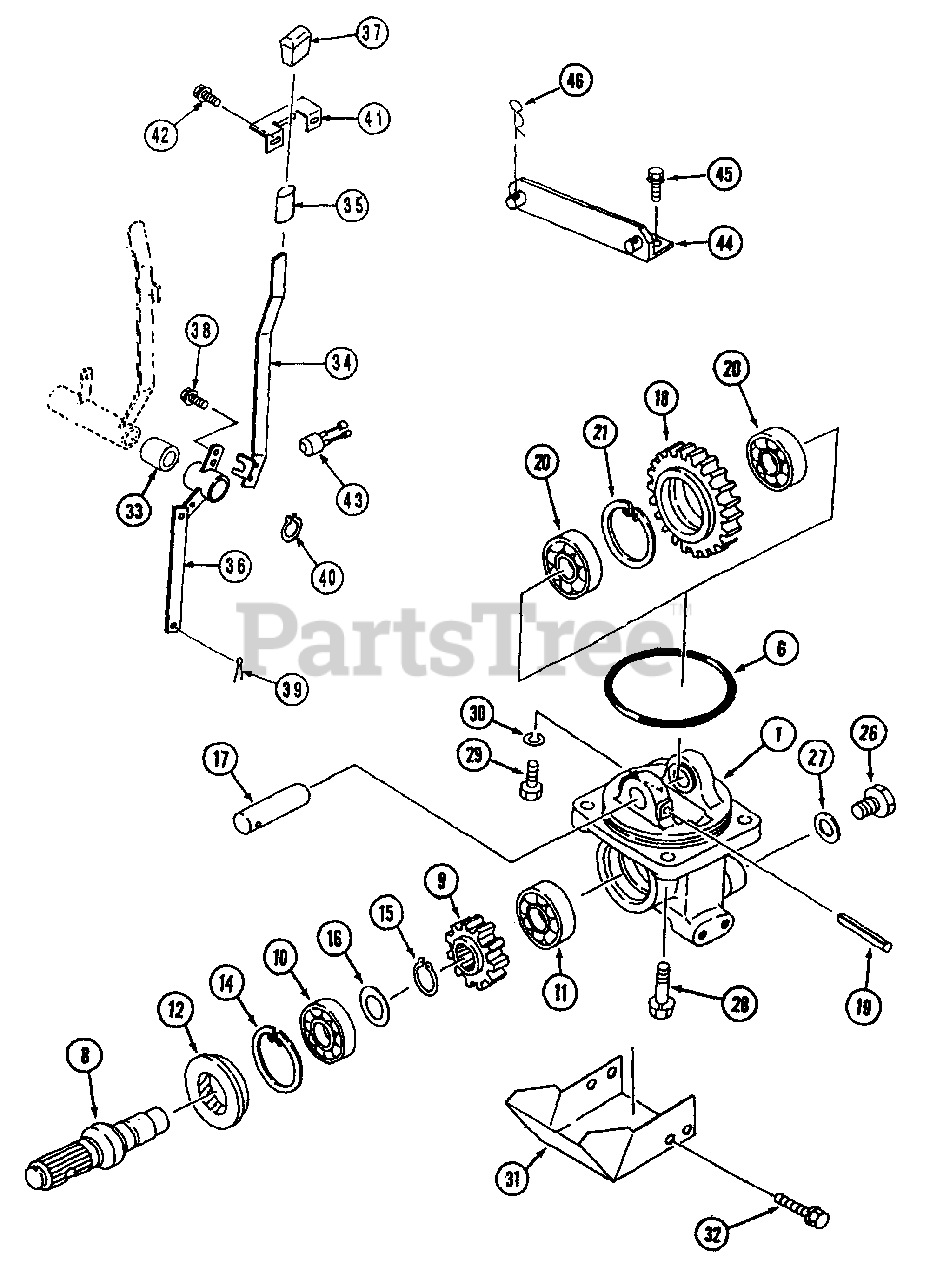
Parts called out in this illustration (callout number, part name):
27	Seal, Washer
34	Lever, Mid PTO
36	Lever, Mid PTO
39	Pin, Split
41	Plate, Mid PTO
44	Bracket, Drawbar
